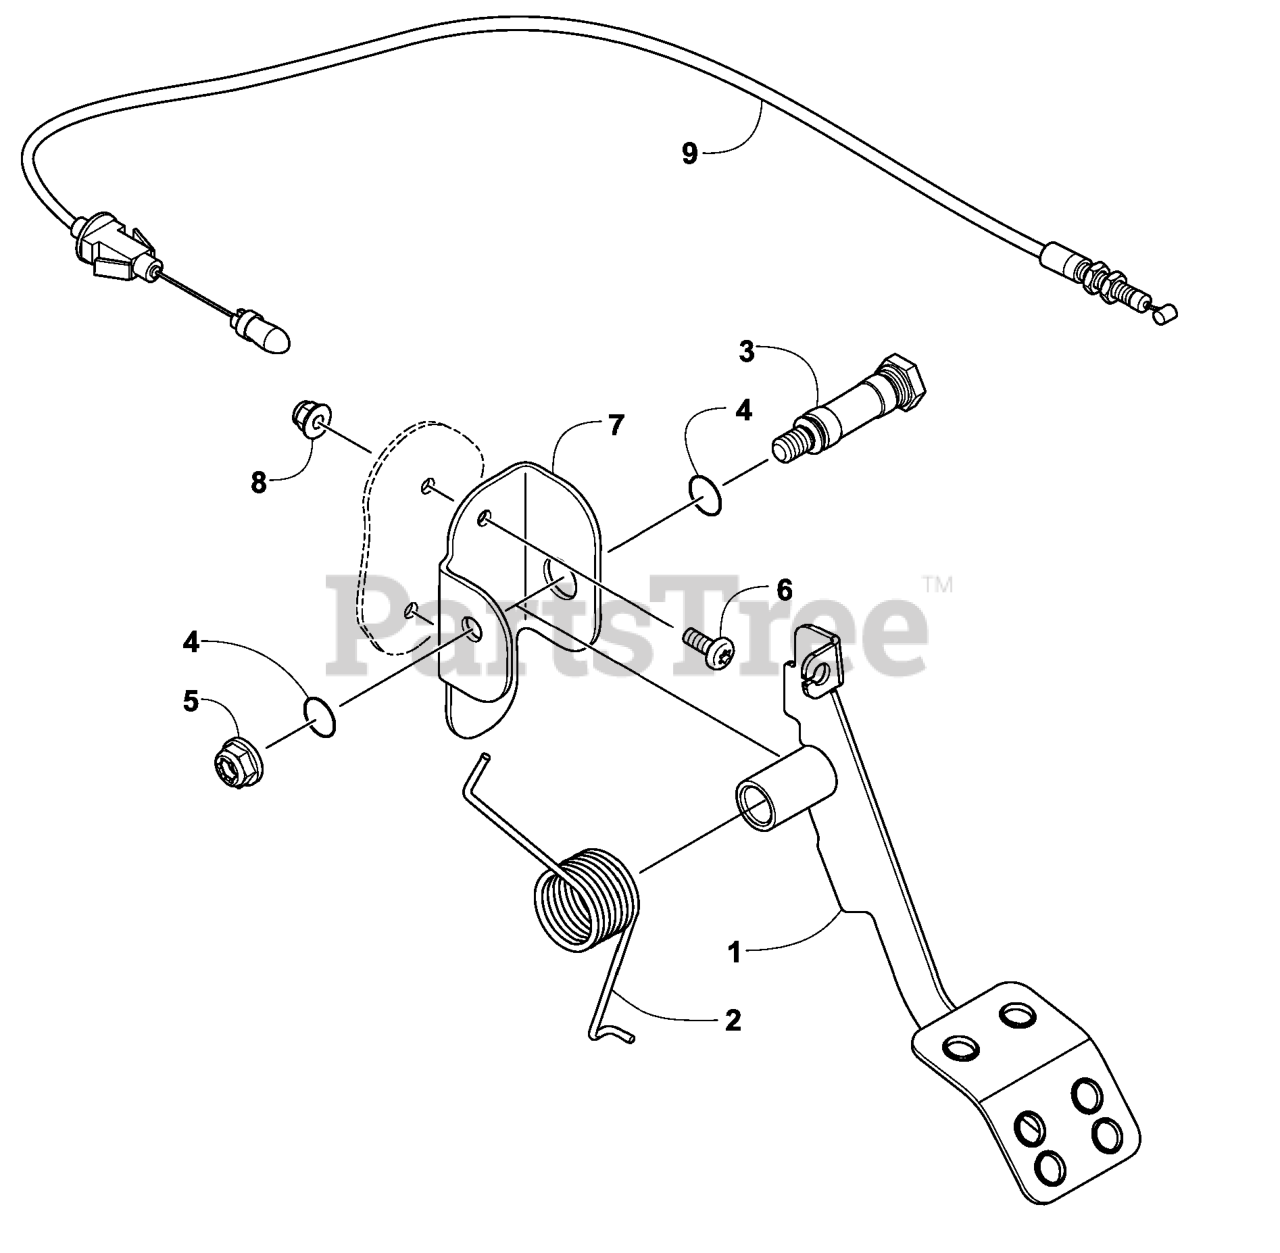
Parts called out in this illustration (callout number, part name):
1	PEDAL-ACCELERATOR
2	SPRING-TORSION
3	AXLE-FOOTBRAKE
6	SCREW-TSPRH
8	LINKAGE,LOWER CALIPER RH
9	CABLE-ACCELERATOR
